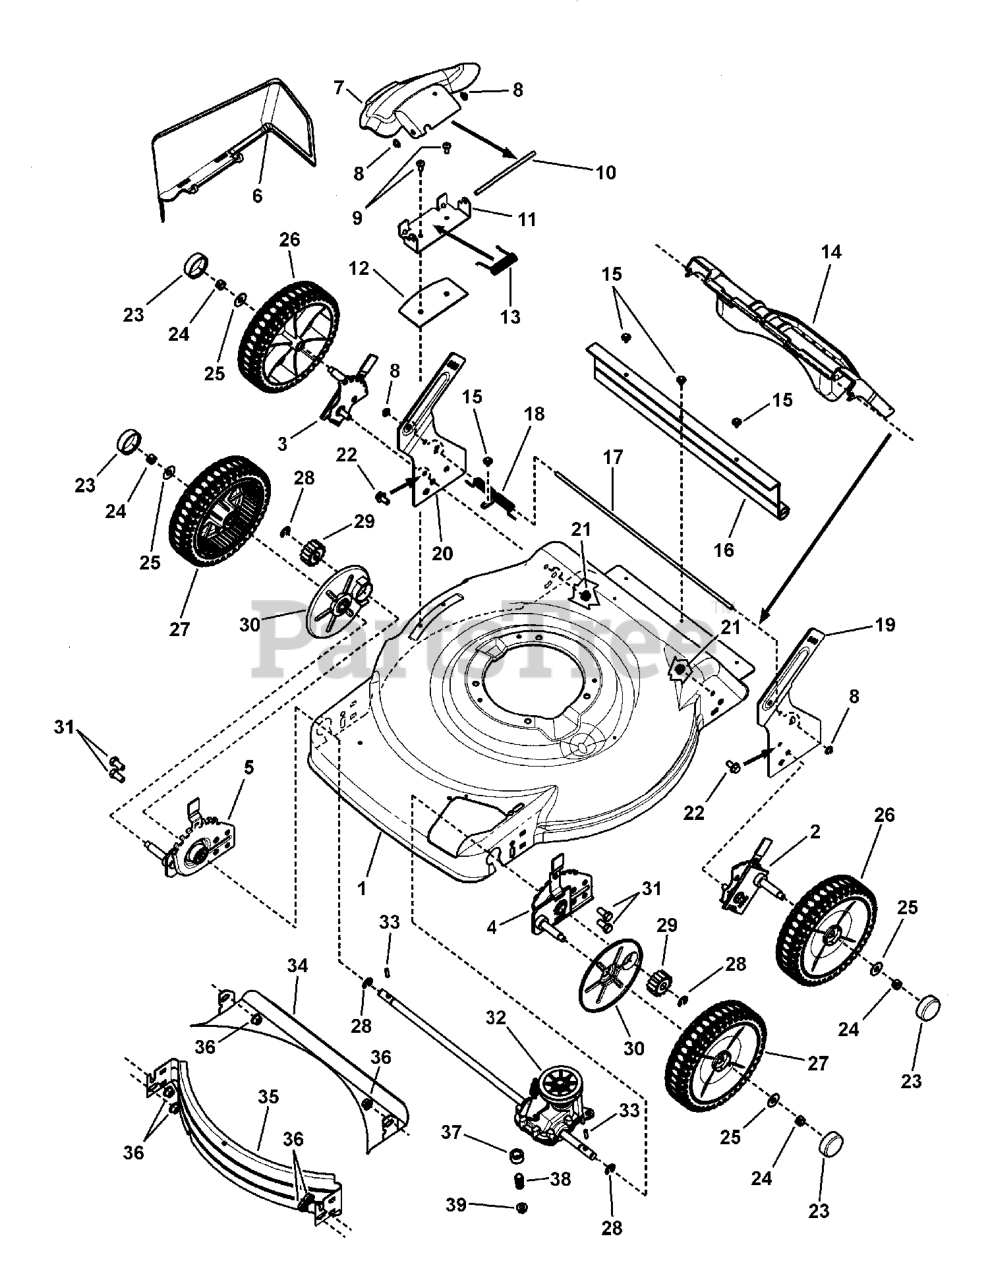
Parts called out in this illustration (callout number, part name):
1	DECK, 22" Walk, 3-N-1
2	ASSY, Height-of-Cut, Left Rear, Murray 7 Position
3	ASSY, Height-of-Cut, Right Rear, Murray 7 Position
4	ASSY, Height-of-Cut, Left Front, 22" WBM, Self-Prop, 7 Position
5	ASSY, Height-of-Cut, Right Front, 22" WBM, Self-Prop, 7 Position
6	SIDE CHUTE, Plastic, Black
7	COVER, Mulch, Plastic, Black
8	PUSHNUT, 1/4"
9	SCREW, 1/4-20 x .550 Pan Head Self-Tap (Torx)
10	ROD, Chute Pivot (1/4" Dia. x 5.55")
11	BRACKET, Chute
12	PLATE, Mulch, 22" RB Scott's
13	SPRING, Chute (Torsion)
14	DOOR, Rear Discharge, 22" Walk Mower
15	SCREW, #10-24 x 1/2" Hex Washer Self-Tap (Sems)
16	GUARD, Rear
17	ROD, Pivot, Rear Door (1/4" Dia. X 17-1/2")
18	SPRING, Torsion, Rear Door, 22" Walk Mower
19	BRACKET, Lower Handle, LH
20	BRACKET, Lower Handle, RH
21	NUT, 5/16-18 Flange Lock, YZ
22	BOLT, 5/16-18 x 5/8" Hex Flange Lock, YZ
23	HUBCAP, Round, Black
24	NUT, 3/8-16 Hex Center Lock, YZ
25	WASHER, 1" O.D. x .387 I.D. Flat
26	ASSY, Wheel, 8" x 2" Idle, NB Murray Tread, Pewter
27	ASSY, Wheel, 8" x 2" Drive, NB, Murray Tread, Pewter
28	RING, External Retaining
29	GEAR, Pinion, 22" WBM, FWD
30	SHIELD, Dust, 22" WBM, FWD
31	SCREW, 3/8-16 x 3/4" Hex Head Cap, GR 5
32	TRANSMISSION, 22" WBM Single Speed, Front Wheel Drive
33	DRIVE PIN, 22" WBM, Front Wheel Drive
34	BAFFLE, Rear, 22" Deck
35	BAFFLE, Front, 22" WBM
36	NUT, 3/8-16 Hex Flange Lock, GR 5
37	SPACER, Drive Transmission
38	SPRING, Compression
39	NUT, 5/16-18 Hex Flange Lock
